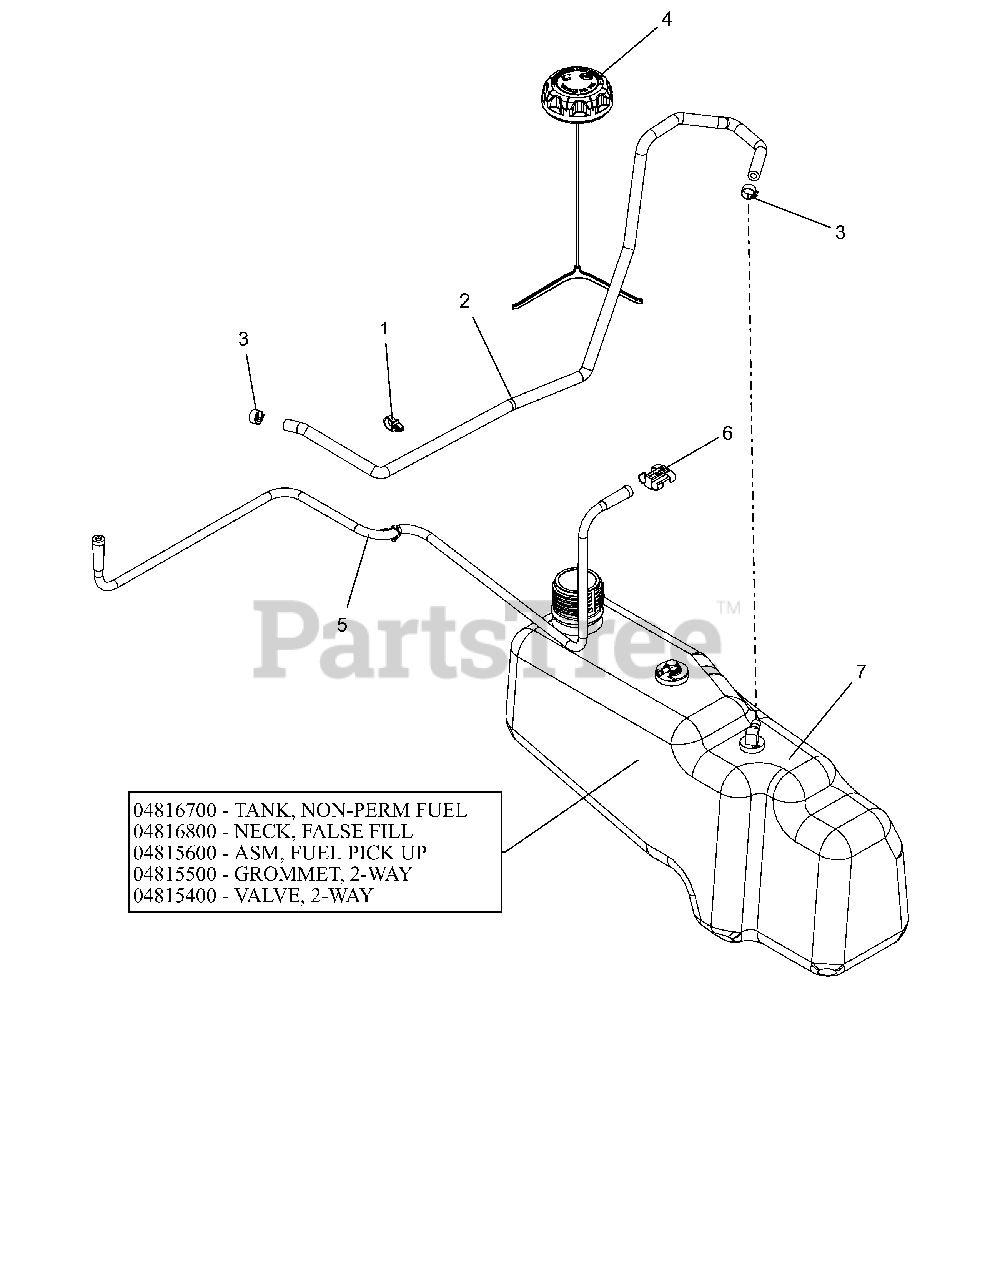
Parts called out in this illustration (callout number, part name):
1	ROUTING CLIP (1/2" ID)
2	HOSE, .25 LOW-PERM BULK GAS
3	CLAMP, FUEL LINE
4	CAP, FUEL VENT-IN 2.25" RATCH.
5	LINE, FUEL VENT KOHLER
6	CLIP, T, .38-.50
7	ASM,TANK NON-PERM FUEL
7	TANK, ZOOM/ZT NON-PERM, FUEL
7	NECK, FALSE FILL ZOOM/ZT
7	ASM, FUEL PICK-UP ZOOM/ZT 2015
7	GROMMET, 2-WAY
7	VALVE, 2-WAY
